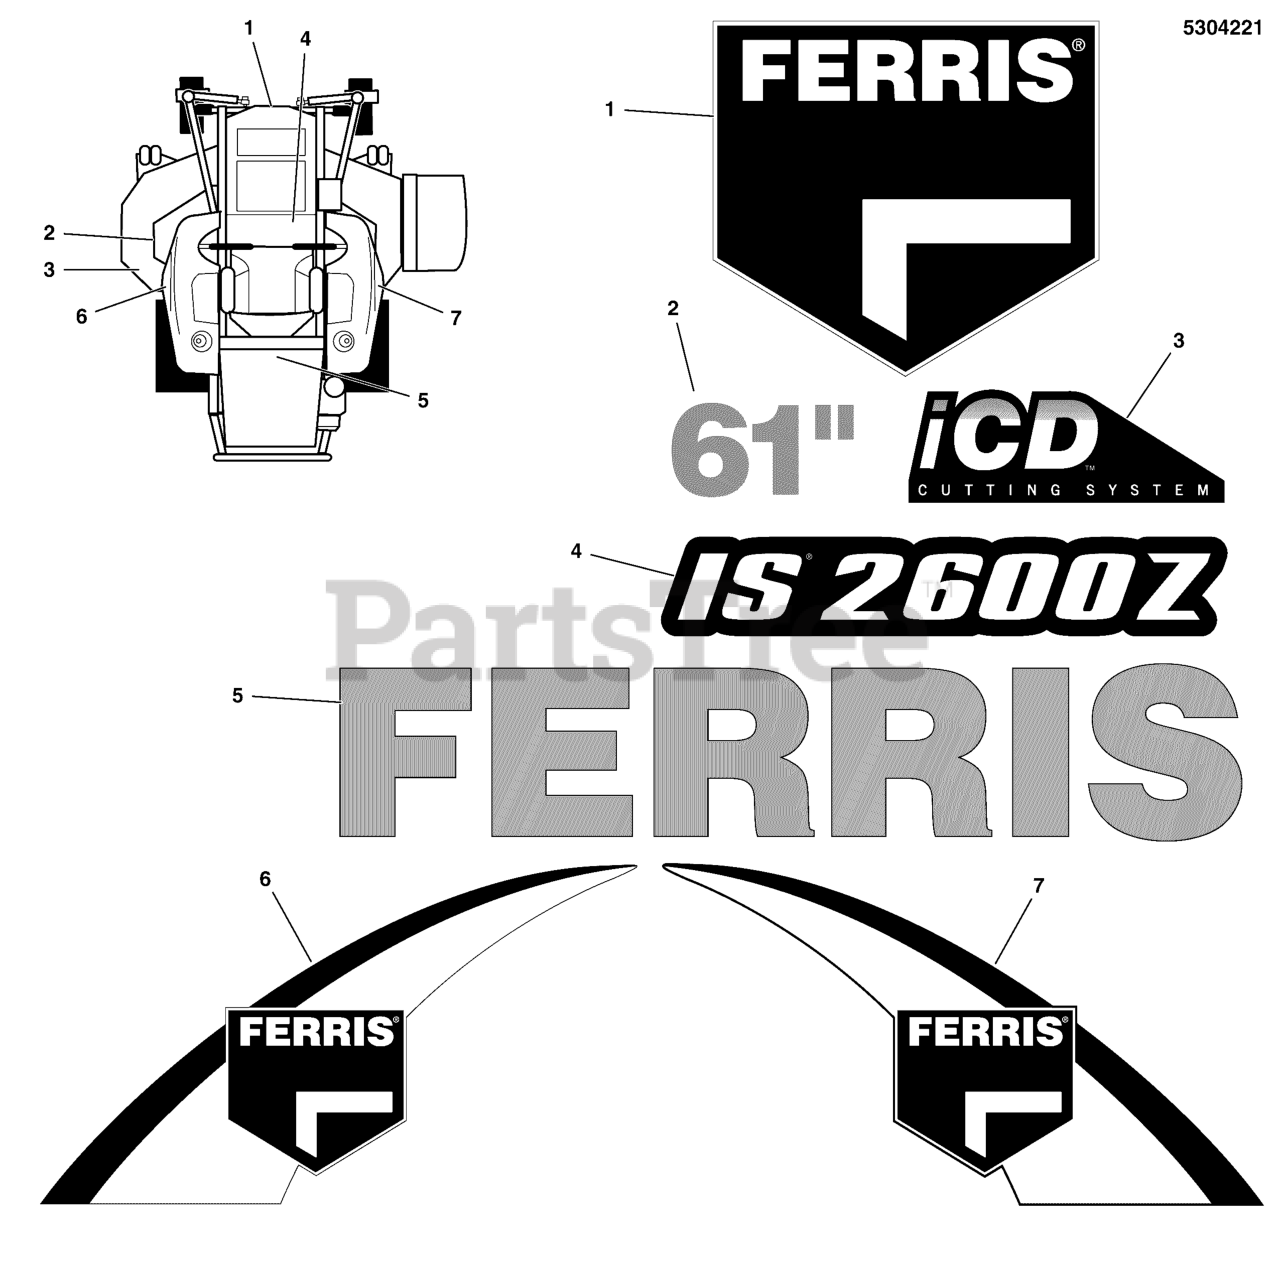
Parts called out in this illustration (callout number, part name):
1	DECAL, FERRIS LOGO, MEDIUM
2	DECAL, 61
3	DECAL, iCD CUTTING SYSTEM
4	DECAL, MODEL
5	DECAL, FERRIS, 2.23" X 11.39"
6	DECAL, TANK, LH, FERRIS
7	DECAL, TANK, RH, FERRIS
